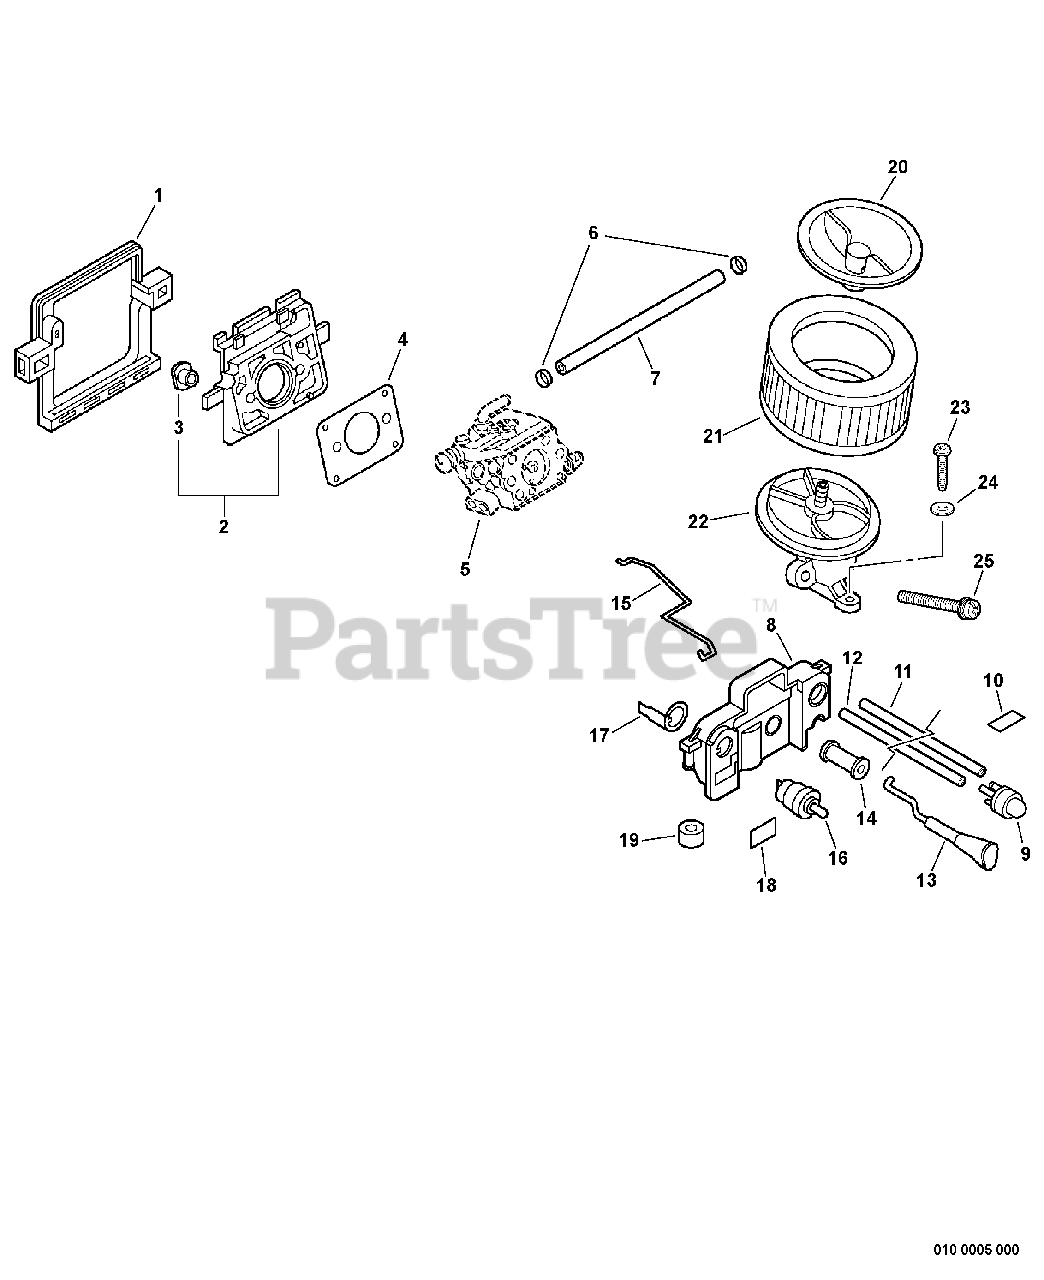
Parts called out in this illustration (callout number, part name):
1	CUSHION
2	INSULATOR
4	GASKET, INTAKE
5	CARBURETOR
6	CLIP 6 MM
7	PIPE, PULSE 2.4×6×105
8	BRACKET, SWITCH
9	BULB, PURGE
10	LABEL, PURGE PUMP
11	PIPE, FUEL 2.4×5×200 BLACK
12	PIPE 2.4×5×105 BLACK
13	ROD, CHOKE
14	GROMMET, CHOKE
15	ROD, THROTTLE
16	SWITCH, ON-OFF
17	TERMINAL - GROUND
18	LABEL, STOP
20	COVER, AIR FILTER
21	FILTER, HEAVY-DUTY AIR
22	ADAPTER, INTAKE
23	SCREW, TAPPING 5×20
24	WASHER, FLAT 5.5×10×0.8
25	SCREW 5×45
